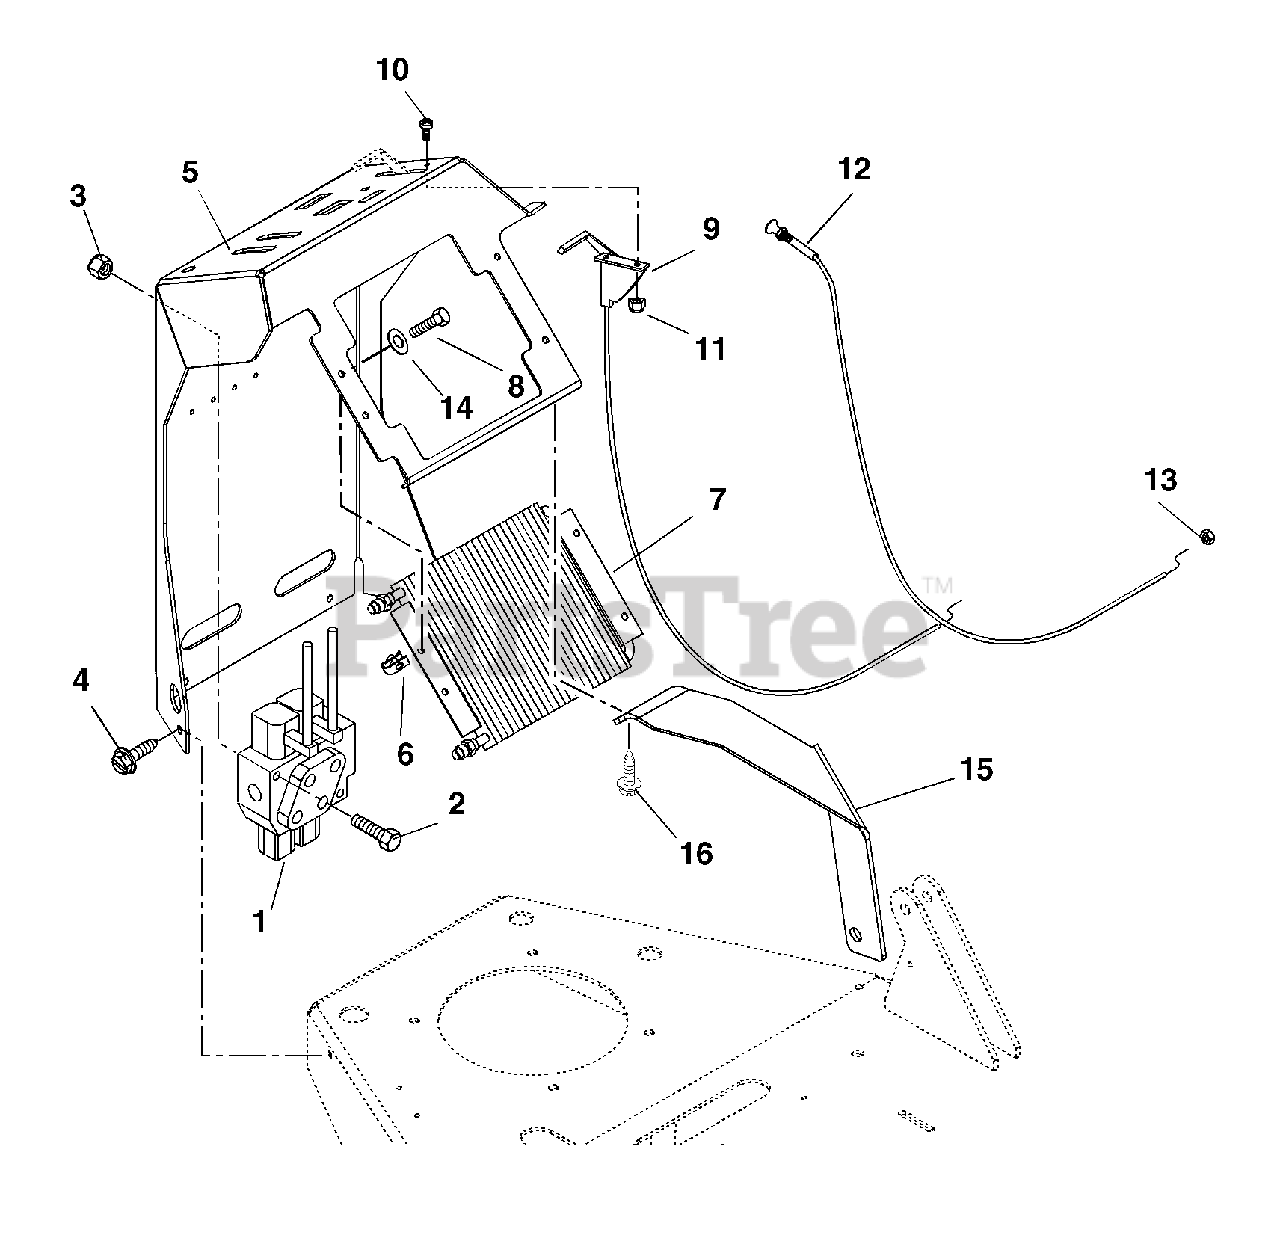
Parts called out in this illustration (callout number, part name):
1	Valve, 2 Spool
2	Bolt-Hex .31-18 x 1.75 Grade 5
3	Nut-Locking-Nylon .31-18
4	Screw-Tapping .38-16 x .75 Hex Washer Head
5	Panel, Control
6	Nut-Retainer .25-20 x .56
7	Cooler, Oil
8	Bolt-Hex .25-20 x .75 Grade 5
9	Cable, Throttle
10	Screw-Machine 10-24 x .50 Hex Washer Head
11	Nut-Locking-Nylon 10-24 with Insert
12	Cable, Choke
13	Nut-Jam .38-24
14	Washer-Flat-Steel .28 x .62 x .065
15	Brace, Instrument Panel-Left Hand
16	Screw-Tapping .25-20 x .50 Hex Washer Head
